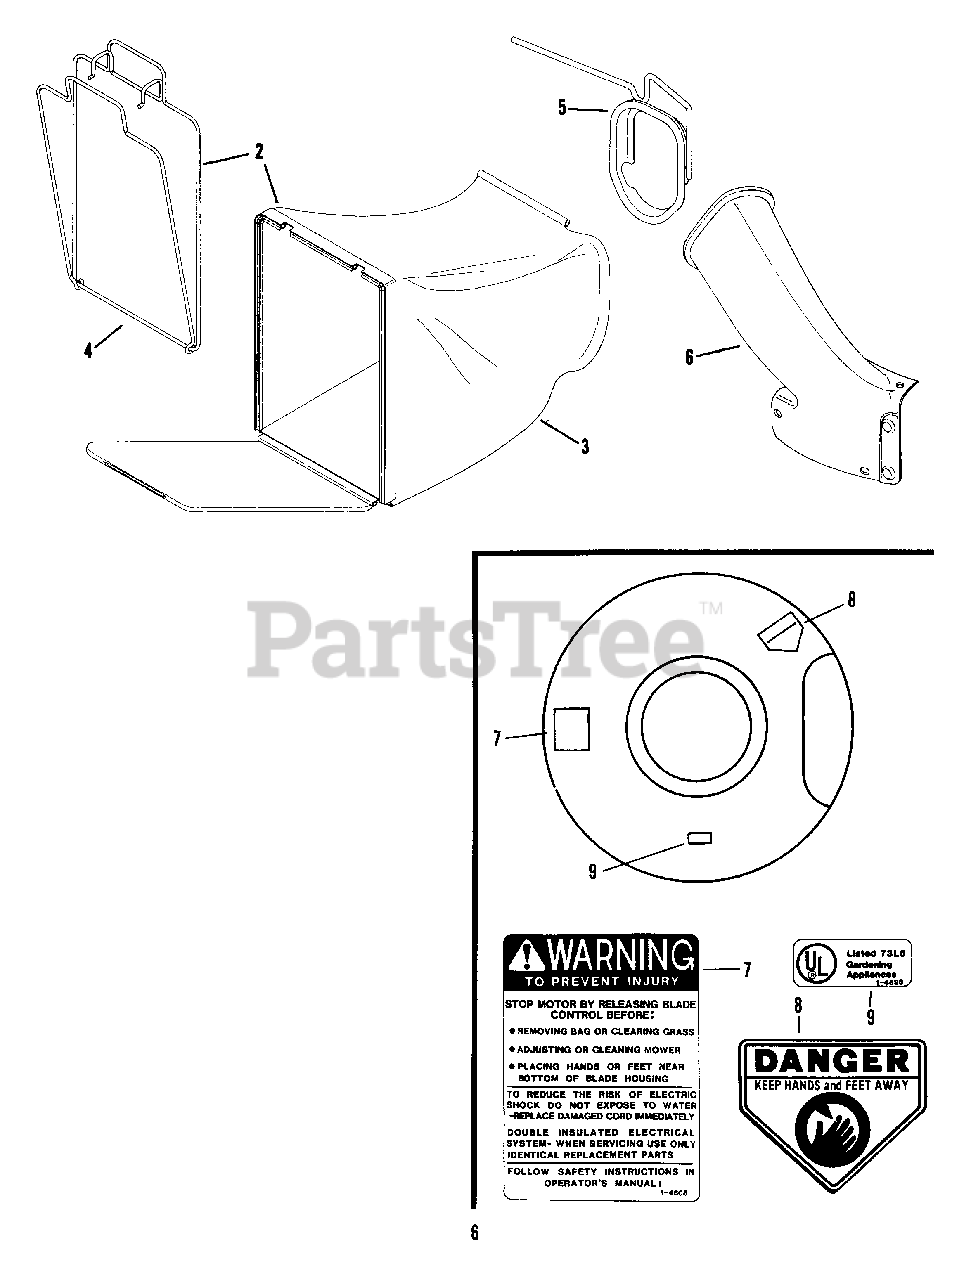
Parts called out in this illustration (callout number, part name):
1	KIT, Grass Bag Catcher
2	ASSEMBLY, Grass Bag
3	BAG, Door Type
4	ASSEMBLY, Bag Wire
5	CONNECTOR, Grass Bag
6	ADAPTER, Grass Bag
7	DECAL, Warning
8	DECAL, CPSC Warning
9	DECAL, UL Listing
